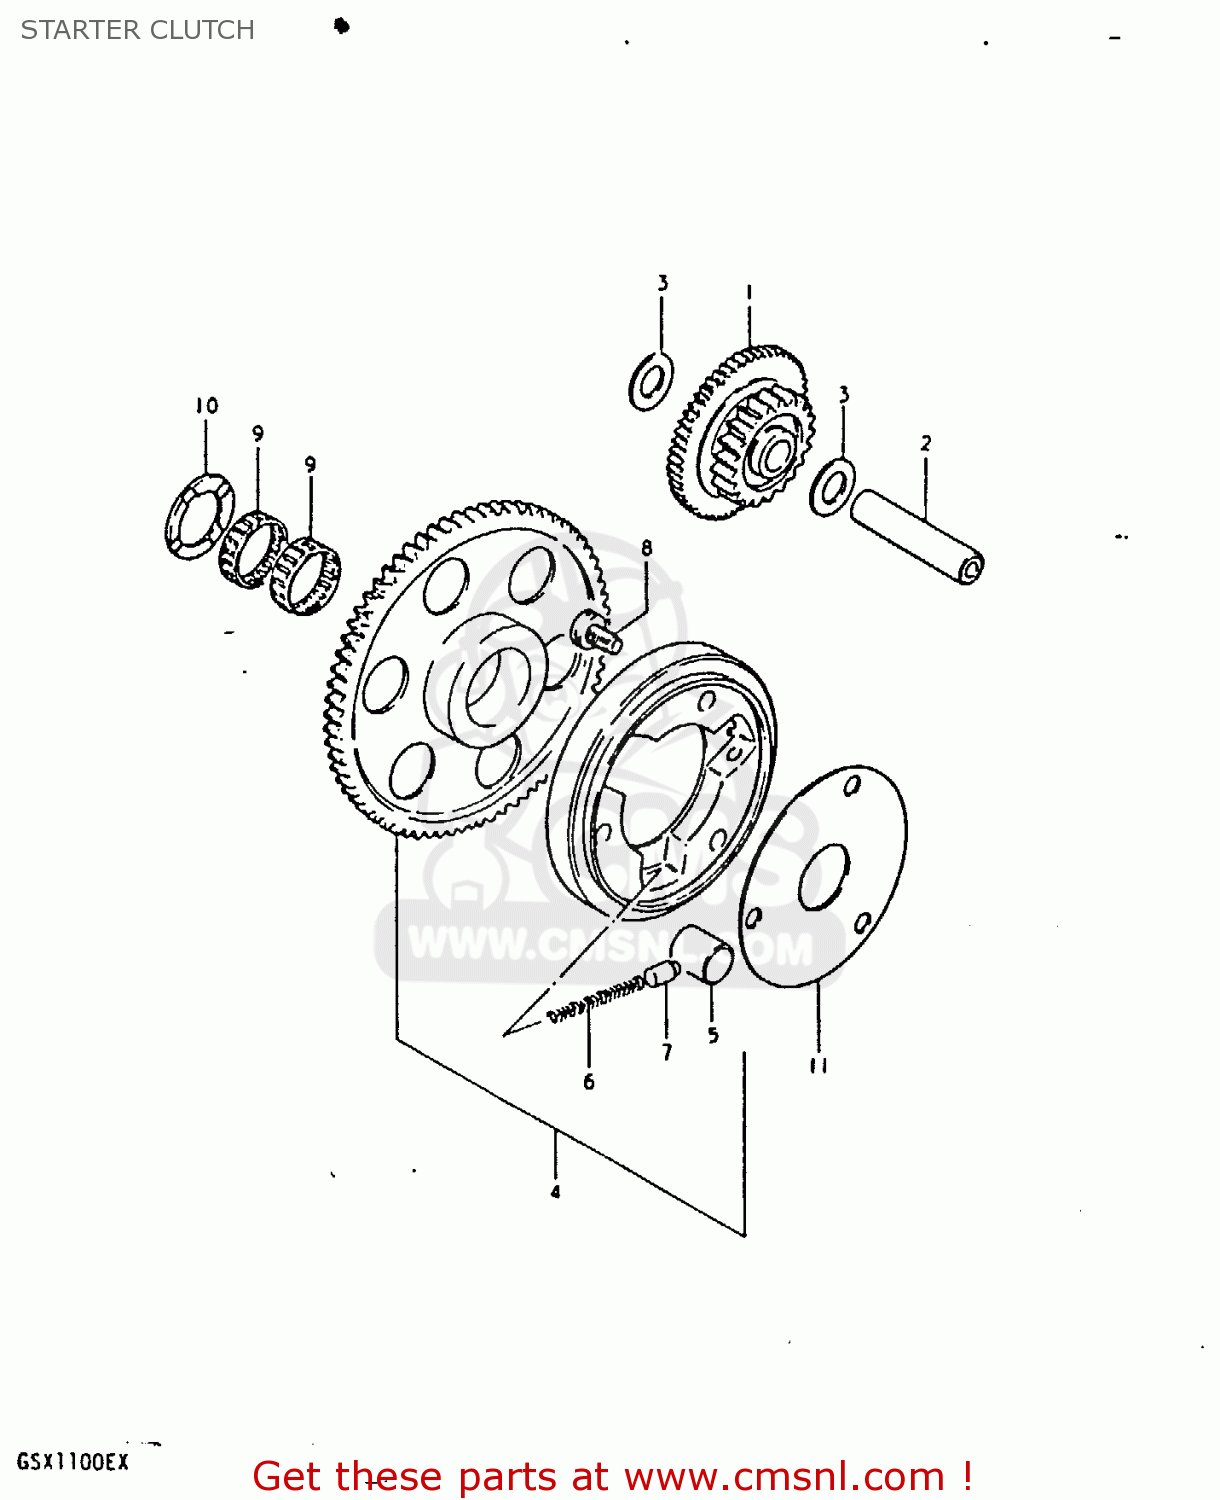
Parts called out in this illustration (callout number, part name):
1	GEAR,STARTER IDLE
2	PIN(7.4X13X56)
3	WASHER(13.3X25X0.85)
4	CLUTCH SET,STARTER
5	ROLLER(15X13)
6	SPRING
7	PIECE,PUSH
8	BOLT
9	BEARING
10	WASHER(25X38X2.5)
11	SHIM,STARTER CLUTCH HUB
